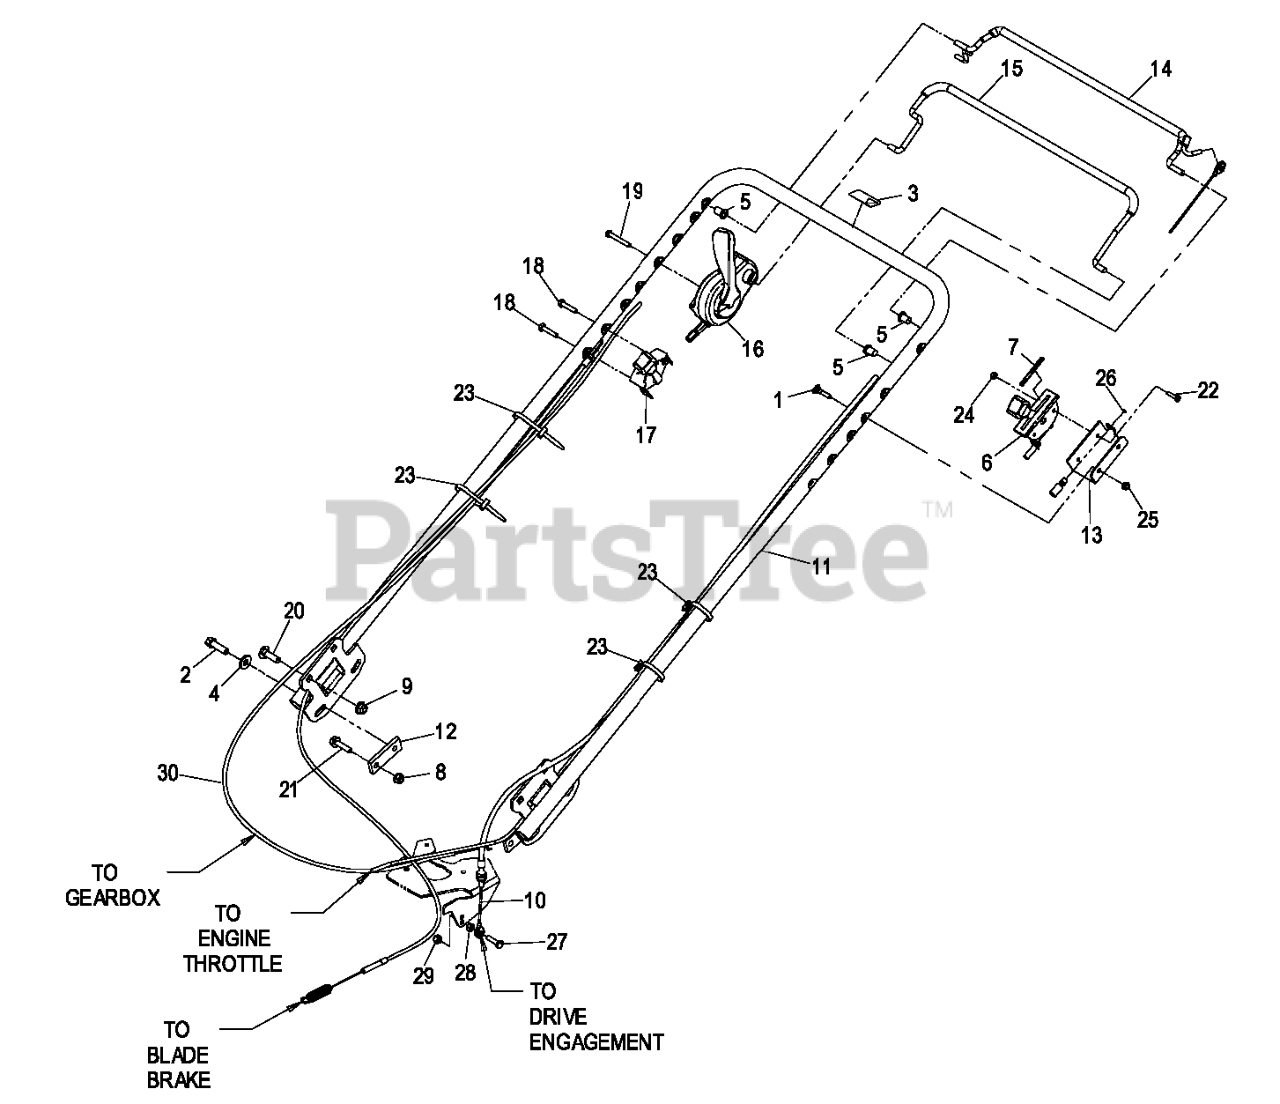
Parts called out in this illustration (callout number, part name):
1	SCREW-HANDLE
2	SCREW-TAPTITE
3	DECAL-PROTECTION, EAR
4	WASHER-BELLEVILLE
5	BUSHING
6	CONTROL-THROTTLE
7	DECAL-THROTTLE / CHOKE
8	NUT-HF, NI
9	NUT-HF, NI
10	CABLE-TRACTION
11	ASM,HANDLE W/DECALS
12	NUT-HANDLE
13	BRACKET-CONTROL
15	BAIL-BBC (WITH GRIP)
16	CONTROL-BBC
18	SCREW-HH
19	SCREW-HH
20	BOLT-CARR
21	SCREW-HHF
22	SCREW-PPH
23	TIE-CABLE
24	NUT-LOCK, NI
25	NUT-LOCK, NI
27	SCREW-HH
28	NUT-HEX
29	NUT-LOCK, NI
30	CABLE-SHIFTER
